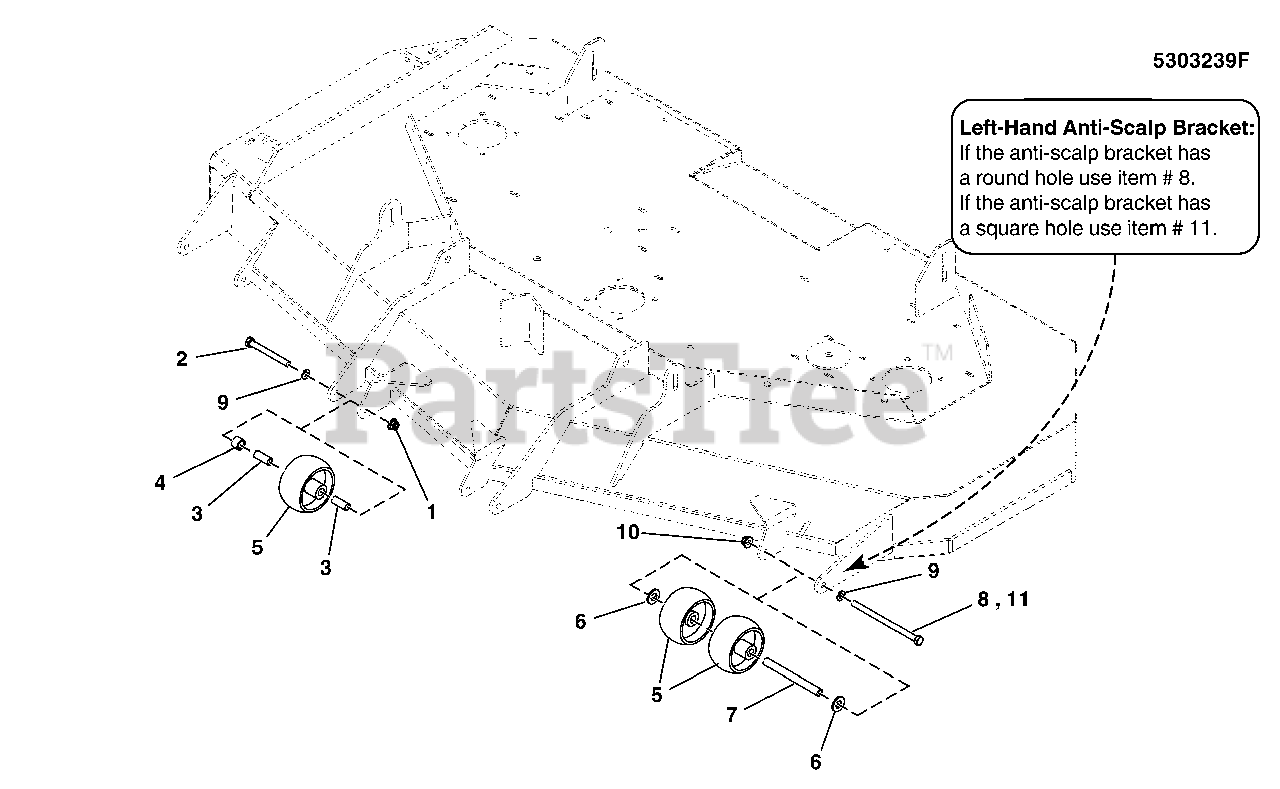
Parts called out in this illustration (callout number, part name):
1	NUT, 3/8-16 HEX NYLOCK FLANGE
2	BOLT, 3/8-16 X 3-1/2 GD5 CZ
3	SPACER, .38 X .50 X 1.25
4	SPACER, .51 X .75 X .56, CZ
5	WHEEL- 2.00 WIDE 3.88 DIA 0.531ID POLY
6	WASHER, 1/2 GD9 YZ
7	SPACER, .38 X .50 X 5.06
8	BOLT, 3/8-16 X 6 GD5 YZ
9	WASHER, 3/8 SAE
10	NUT, 3/8-16 HEX SIDE LOCK
11	BOLT, CARRIAGE, 3/8-16 X 6, GD5, CZ
